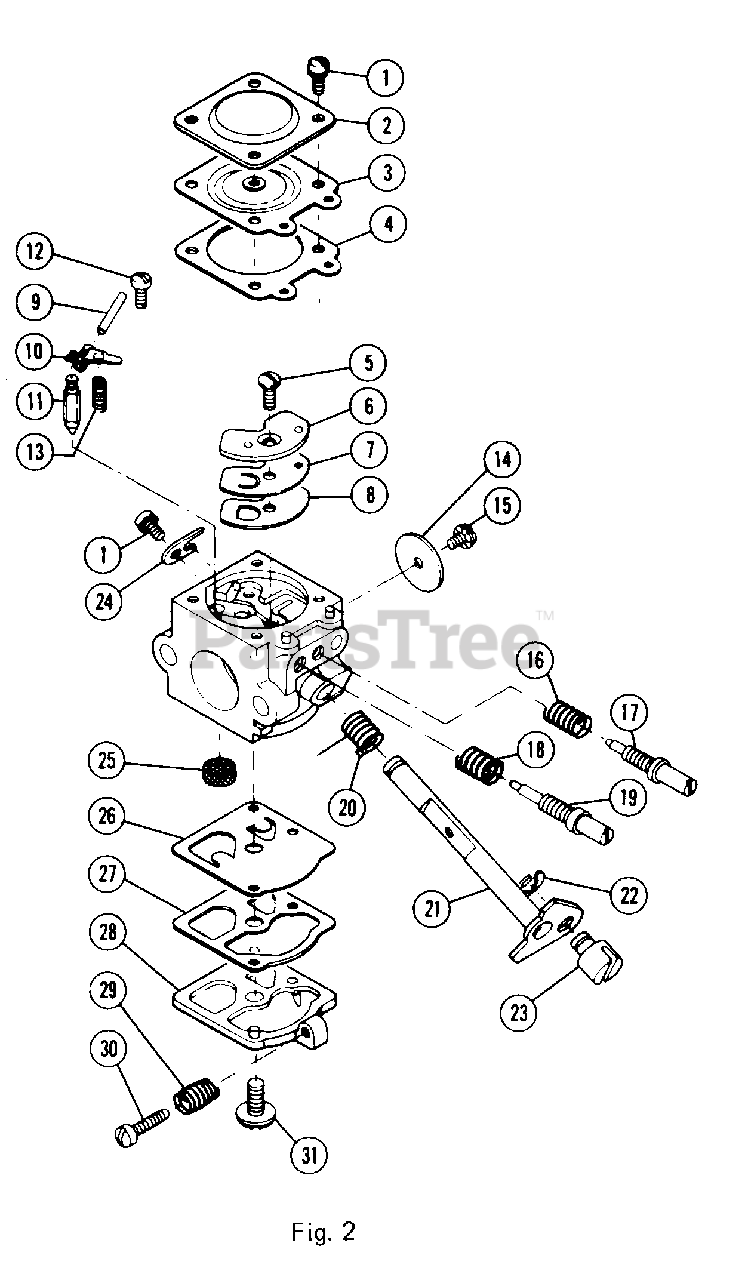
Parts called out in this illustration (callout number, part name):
1	Screw & lock washer
2	Metering diaphragm cover
3	Metering diaphragm
4	Metering diaphragm gasket
5	Circuit plate screw
6	Circuit plate
7	Circuit diaphragm
8	Circuit plate gasket
9	Metering lever pin
10	Metering lever
11	Inlet needle valve
12	Metering lever pin screw
13	Metering lever spring
14	Throttle valve
15	Shutter screw
16	I. needle adjust spring
17	Idle needle
18	H.S. needle adjust spring
19	H.S. needle
20	Throttle return spring
21	Throttle shaft
22	Swivel clip
24	Throttle shaft clip
25	Inlet screen
26	Pump diaphragm
27	Pump gasket
28	Pump cover
29	Idle adjust spring
30	Idle adjust screw
31	Pump cover screw
